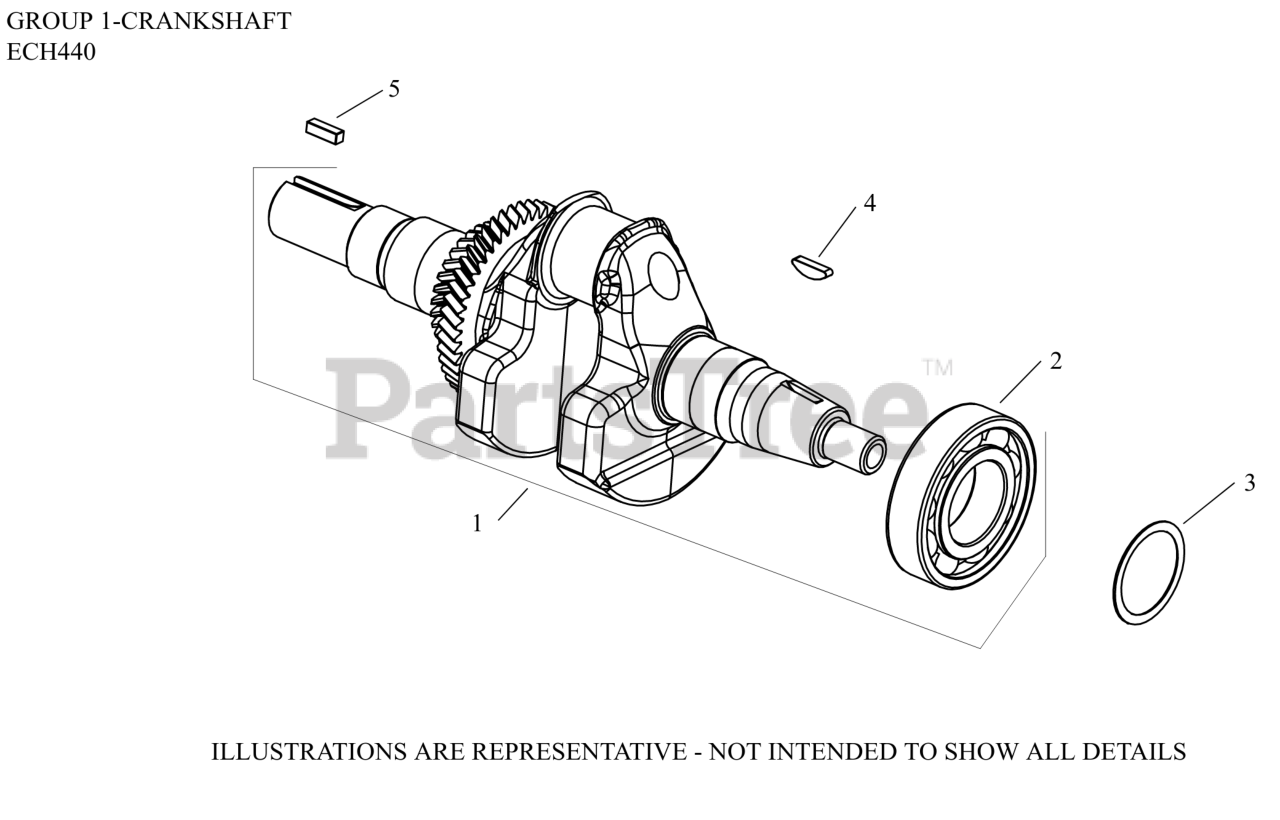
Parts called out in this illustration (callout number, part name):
1	CRANKSHAFT ASSEMBLY-USE 17 014 207-S
2	BEARING, CRANKSHAFT-(1703034S)
3	KIT, SHIM
4	KEY, FLYWHEEL
5	KEY, SQUARE
